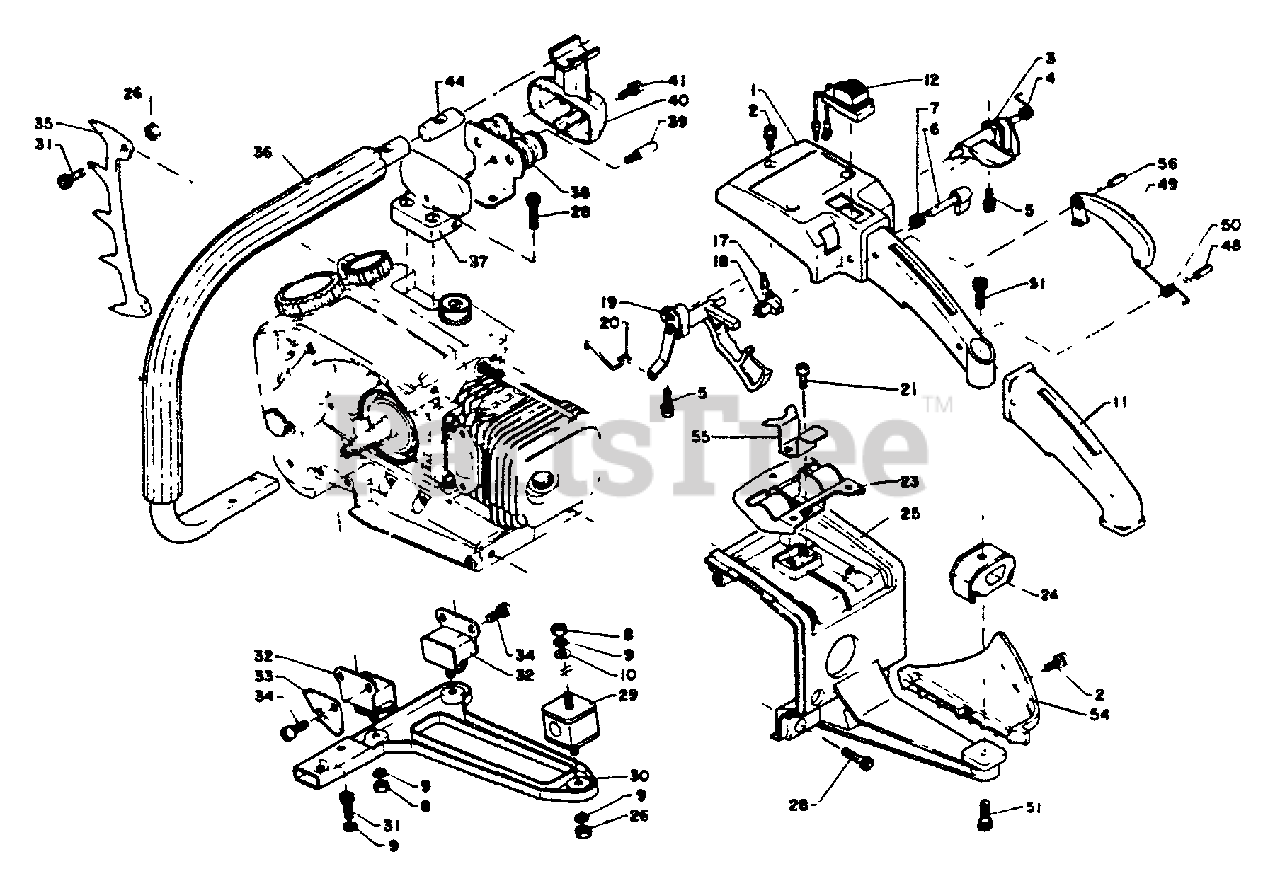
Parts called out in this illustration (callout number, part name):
1	HANDLE - REAR
2	SCREW - 4X14
3	Push lever
5	SCREW - 4X14
6	LEVER, THROTTLE
7	SPRING, LOCKOUT LEVER
9	LOCKWASHER - 5
10	WASHER - 5
11	GRIP
12	IGNITION SWITCH ASSY
17	PIN - LOCKING
18	LOCKOUT, THROTTLE
19	TRIGGER, THROTTLE
20	ROD, THROTTLE
21	SCREW - 5X12
24	CUSHION
25	COVER, ENGINE
26	LOCKNUT - 5
28	SCREW - 5X20
29	Cushion rubber (L-L: 2)
30	BRACKET, HANDLE - LOWER
31	SCREW - 5X12
32	Cushion rubber (L-L)
34	SCREW - 5X12
35	SPIKE
36	HANDLE - FRONT
37	Cushion rubber holder
38	Cushion (L-U)
40	BRACKET, HANDLE - UPPER
41	SCREW - 4X10
48	PIN - SPRING -- 4X13
49	LOCKOUT, THROTTLE
50	SPRING, LOCKOUT LEVER
51	SCREW - 5X14
54	GUARD, HAND
55	CUSHION
56	PIN - SPRING -- 4X16
